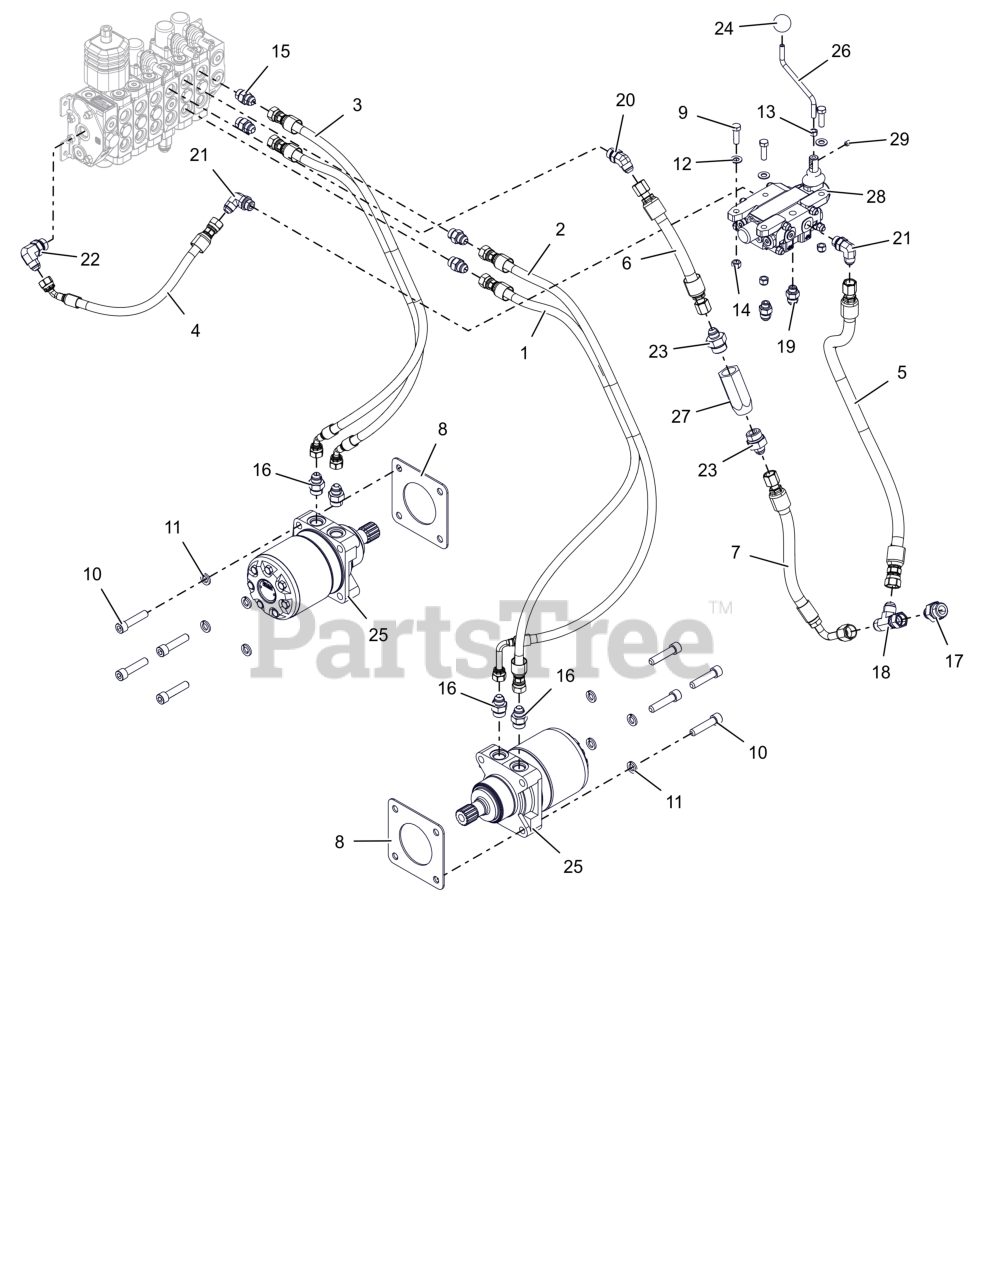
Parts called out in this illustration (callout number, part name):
1	HOSE, HYD .375" X 48.00" LG
2	HOSE, HYD .375" X 48.75" LG
3	HOSE, HYD .375" X 41.25" LG
4	HOSE, HYD .375" X 17.75" LG
5	HOSE, HYD .500" X 31.50" LG
6	HOSE, HYD .500" X 10.50" LG
7	HOSE, HYD .500" X 16.00" LG
8	GASKET, MOTOR HYD
9	BLT, HEX .38-16X1.25 G5 ZCC
10	SCR, SKH .500-13X2.250 GR8 ZCC
11	WSHR,LK-REG 0.502 X 0.125 ZCC
12	WSHR,FLT .406X.812X.065 ZCC
13	NUT, HEX M8-1.25 G8.8 ZCC
14	NUT,NYL .38-16 G5 ZCC
15	FITTING, HYDRAULIC 6400 8-8
16	FITTING, HYDRAULIC 6400 8-10
17	FITTING, HYDRAULIC 6400 10-12
18	FITTING, HYDRAULIC 6602 10-10-10
19	FITTING, HYDRAULIC 6400 8-6
20	FITTING, HYDRAULIC - 6802 8-8
21	FITTING, HYDRAULIC 6801 8-8
22	FITTING, HYDRAULIC - 6801 8-10
23	ADAPTER, 8MJ-12MB
24	KNOB, BALL -.312" PRESS ON
25	MOTOR, HYDRAULIC
26	LEVER, AUXILIARY
27	VALVE, HYD -CHECK 72 PSI
28	VALVE, CONTROL - AUX
29	SCR-SET, 1.50-6X1.500 CUP
